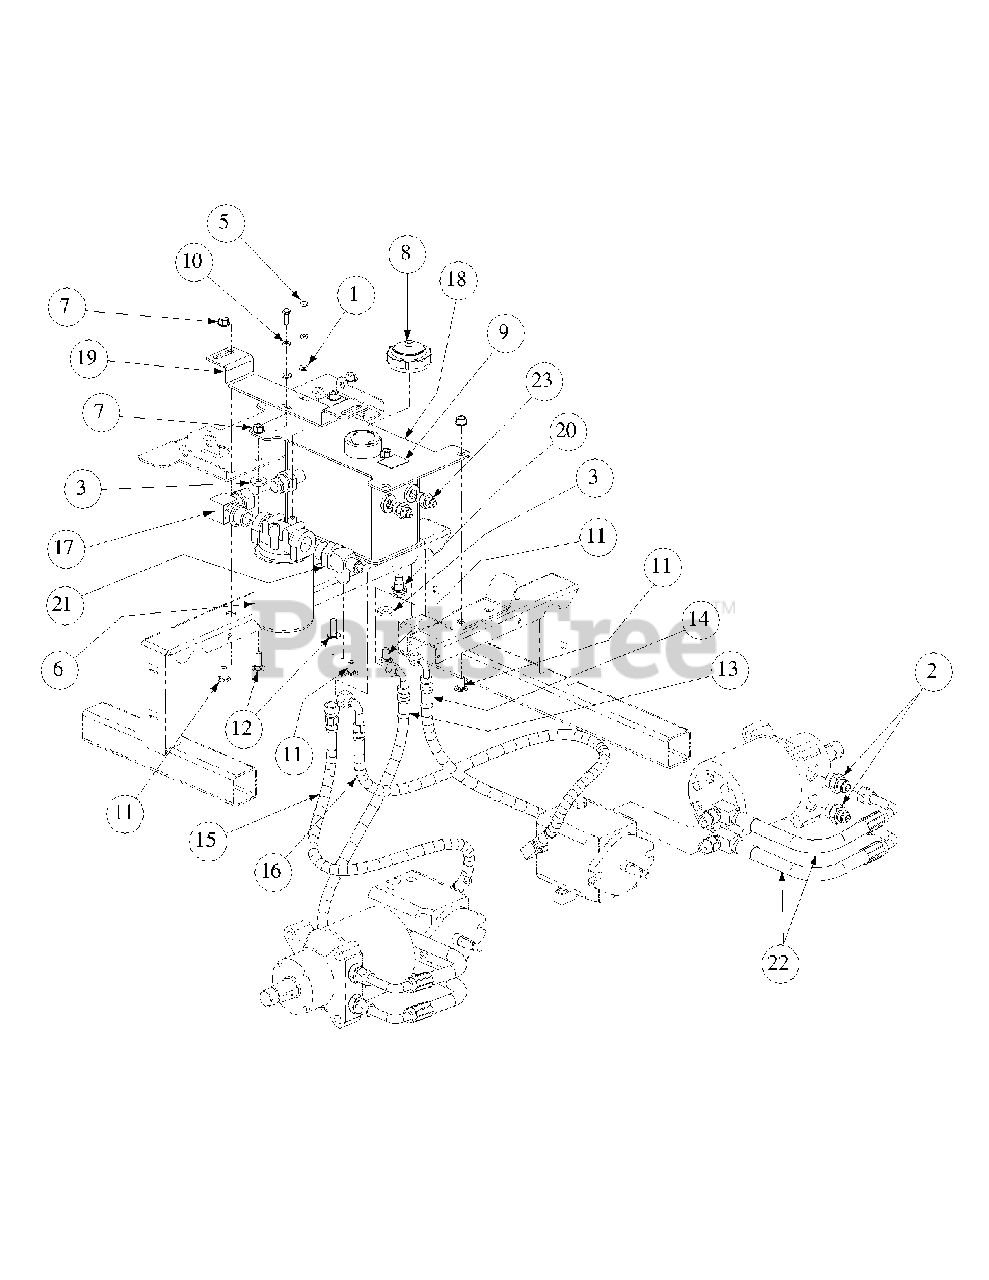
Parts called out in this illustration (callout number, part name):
1	Washer, 1/4
2	Fitting 1/2 x 3/4 - O Ring
3	Washer, .406 x 1.0 OD x .105
4	Cable Tie, 3/16 x .05 x 7.4
5	Hex Cap Screw, 1/4-20, .75
6	Filter Head 3/4
7	Hex Nut Flange Lock, 3/8-16
8	Cap, Hydro Oil Tank
9	Decal Oil Only 5W40
10	Lock Washer, 1/4
11	Carriage Bolt, 3/8-16 x .75 LG.
12	Carriage Bolt, 3/8-16 x 1.00
13	28.87" Return Hose Assembly
14	31.88" Return Hose Assembly
15	29.25" Supply Hose Assembly
16	40.31 Supply Hose Assembly
17	Fitting Elbow, 90
18	Hydraulic Tank Assembly
19	Filter Mounting Bracket
20	Oil Pan Drain w/ Seal and Plug
21	Tee Fitting, 3/4 x 1/2 x 1/2
22	Hydraulic Hose
23	Fitting 1/2 x 3/8
